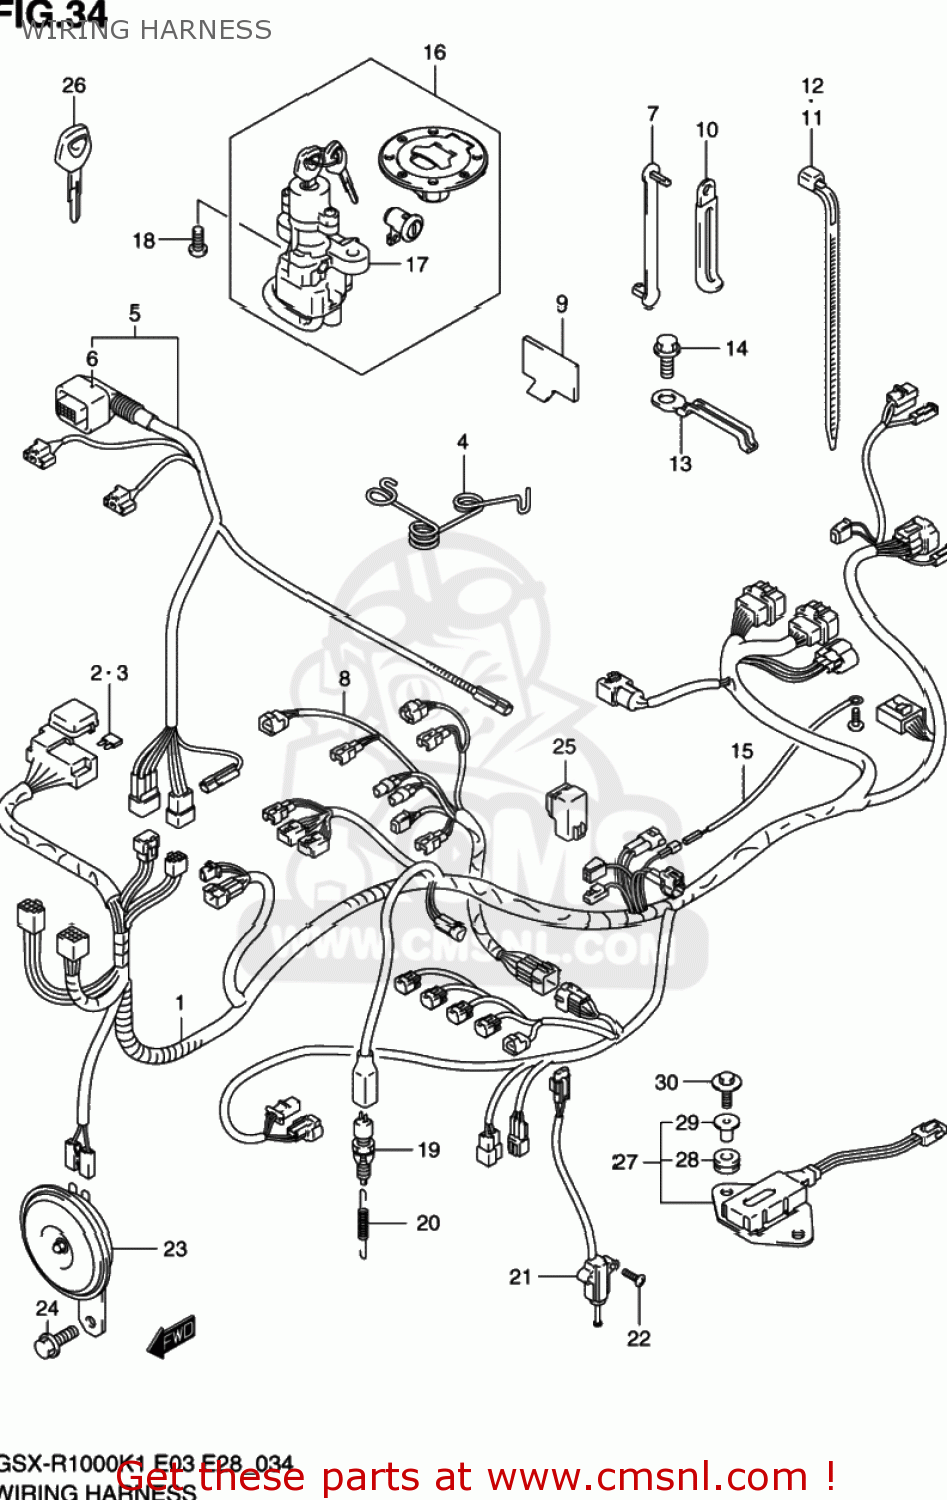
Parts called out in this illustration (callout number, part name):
1	HARNESS,WIRING NO.1
2	FUSE(10A)
3	FUSE(15A)
4	GUIDE,WIRING HARNESS
5	HARNESS,WIRING NO.2
6	COVER,SPEEDOMETER COUPLER
7	CLAMP(L:63)
8	WIRE,INJECTION LEAD
9	PROTECTOR,WIRING HARNESS
10	CLAMP(L:65)
11	CLAMP(L:235)
12	CLAMP
13	CLAMP
14	BOLT
15	WIRE,OIL PRESSURE SWITCH LEAD
16	LOCK SET
17	LOCK ASSY,STEERING
18	BOLT(8X20)
19	SWITCH ASSY,STOP LAMP
20	SPRING
21	SWITCH ASSY,SIDE STAND
22	BOLT
23	HORN ASSY
24	BOLT
25	RELAY ASSY
26	KEY,BLANK
27	RESISTOR ASSY
28	CUSHION
29	SPACER(6.5X10X11.6)
30	BOLT(6X25)
